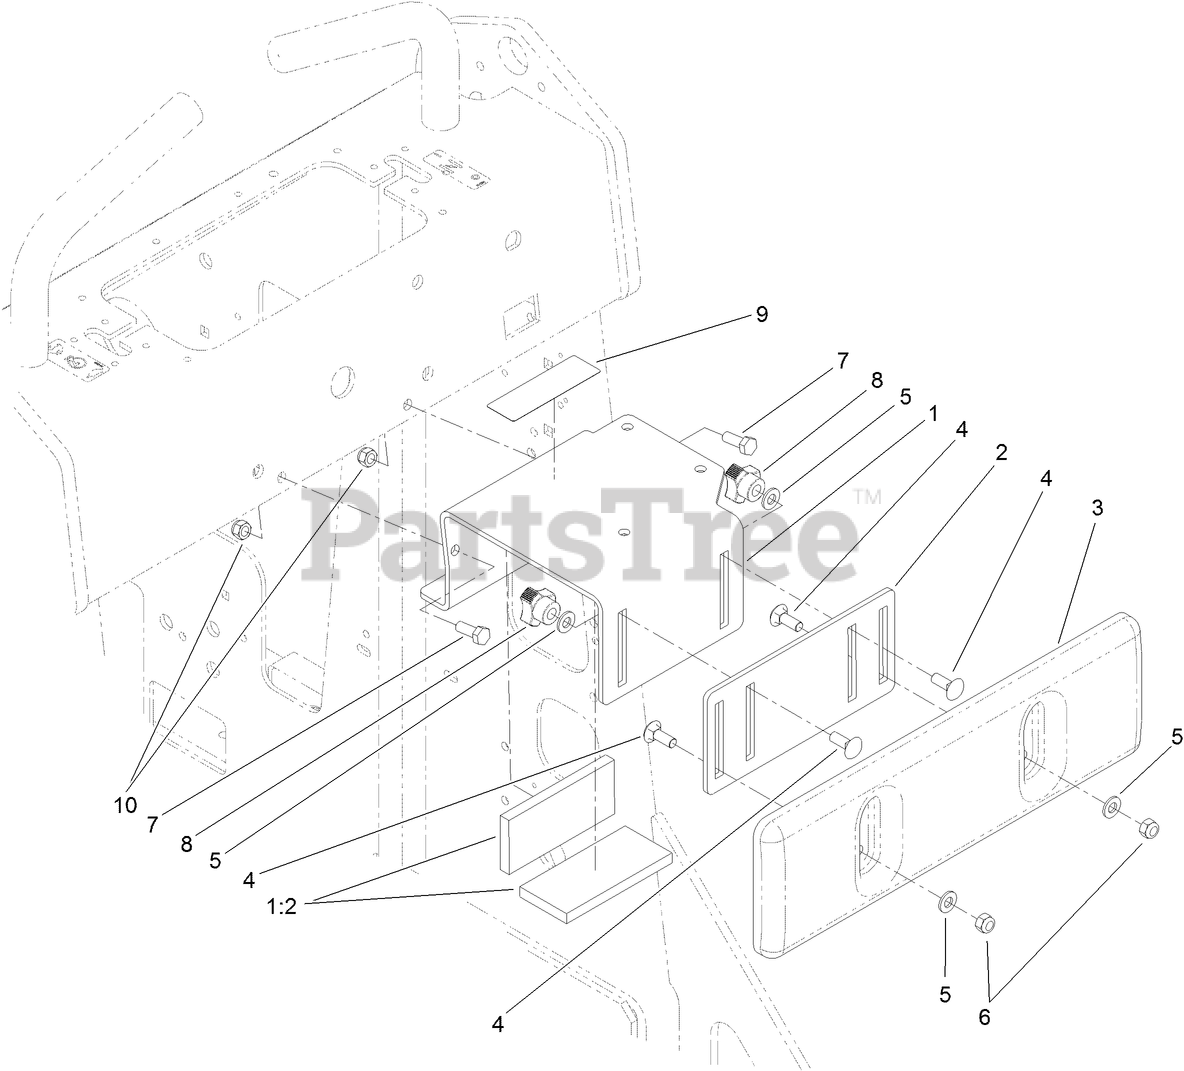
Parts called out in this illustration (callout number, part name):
1	THIGH SUPPORT BRACKET ASM
1:2	PAD-FOAM
2	PLATE-ADJUSTING
3	SUPPORT-THIGH
4	SCREW-CARR
5	WASHER-FLAT
6	NUT-LOCK, NI
7	SCREW-HH
8	Knob-Adjustment
9	DECAL-MANUAL
10	NUT-HF
